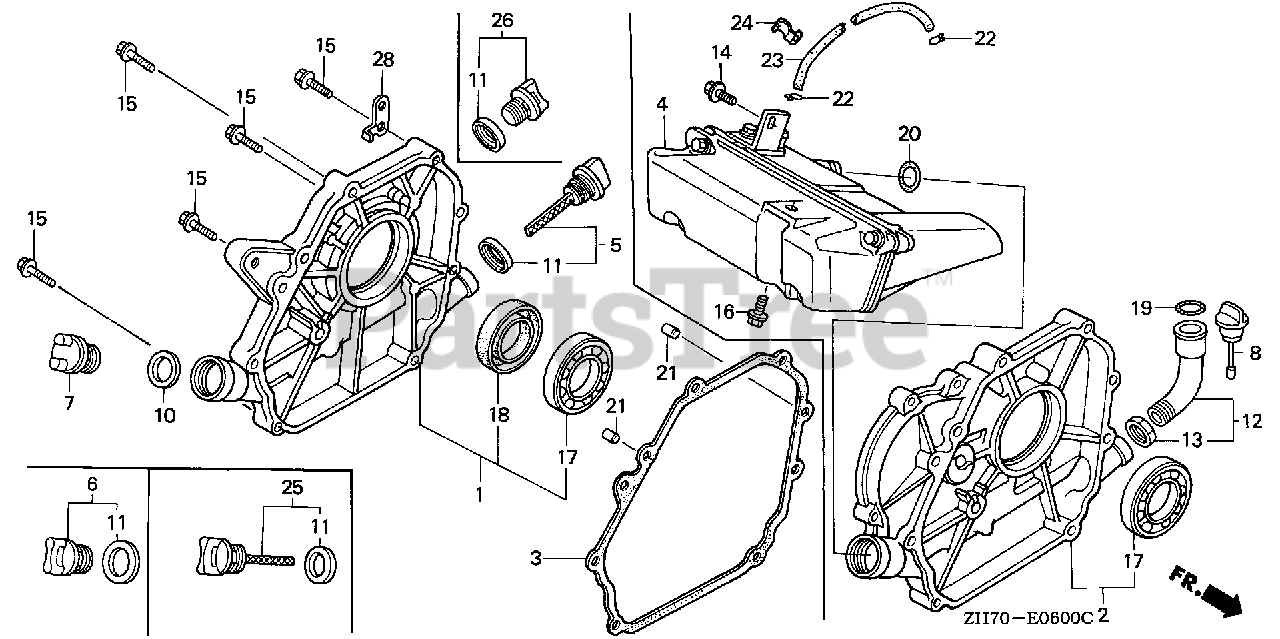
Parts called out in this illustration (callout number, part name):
1	COVER ASSY., CRANKCASE
3	GASKET, CASE COVER
5	CAP ASSY., OIL FILLER (GRAY)
6	CAP ASSY., OIL FILLER
7	CAP, OIL FILLER
10	GASKET, OIL FILLER CAP
11	GASKET, OIL FILLER CAP
15	BOLT, FLANGE (6X28) (CT200)
17	BEARING, RADIAL BALL
18	OIL SEAL (22X41X6)
21	PIN, DOWEL (8X14)
